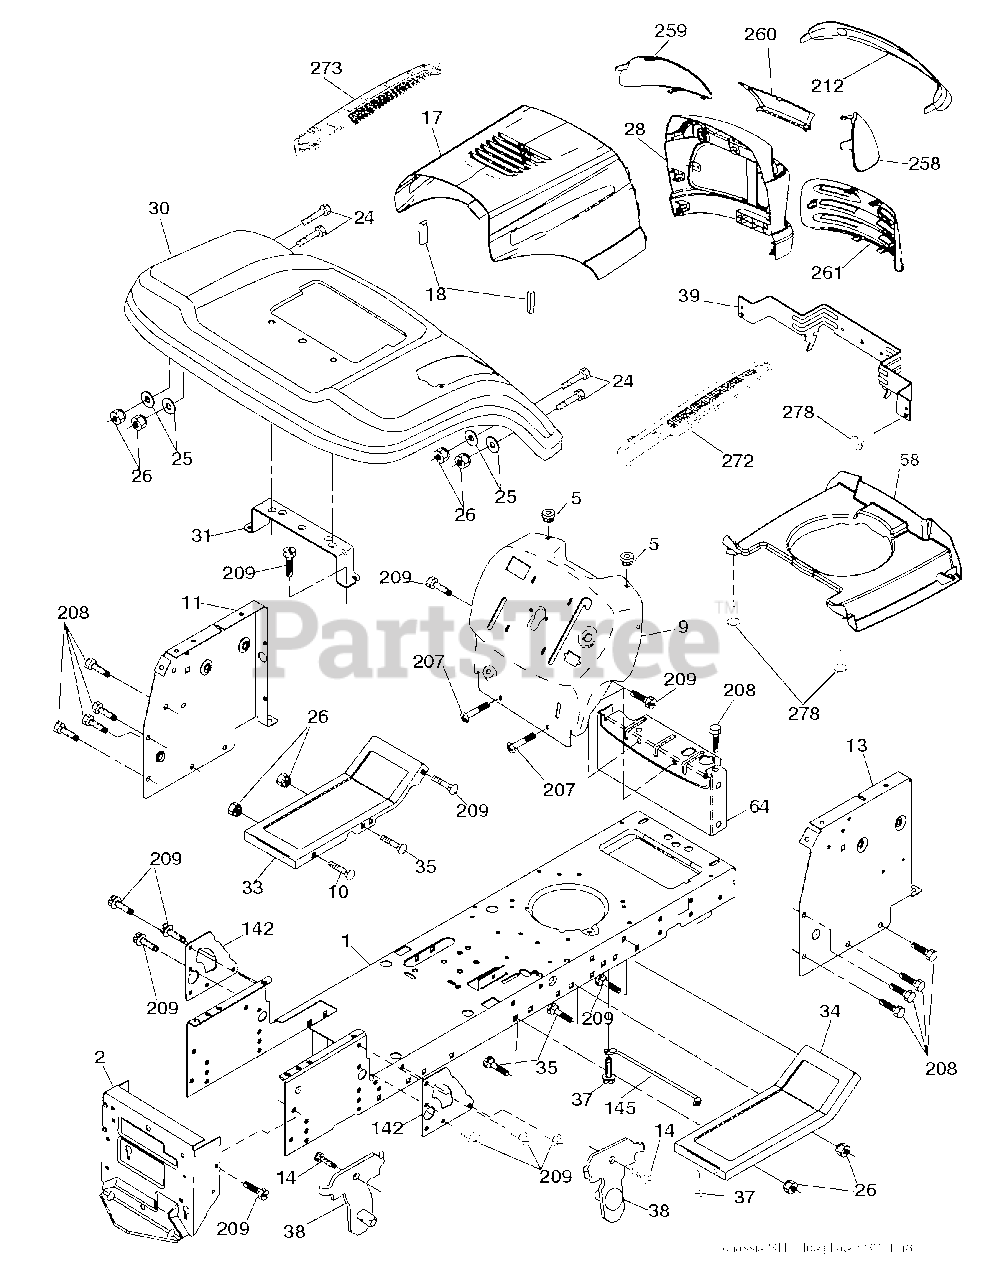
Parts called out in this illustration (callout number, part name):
1	CHASSIS STAMPING
2	DRAWBAR, 12GA
5	BUMPER.RUBBER.HOOD
9	DASH.STL.PLM.CAB.N/AMM.N/HM.05
10	BOLT D
11	PANEL.DASH.LH.LTX
17	HOOD.PNT.LASER.SV.LT.668
18	BUMPER.HOOD.LARGE.1.75"
25	WASHER
26	NUT
28	GRILLE.HUSQ.LASER.LT.668
30	FENDER.PNT.LTST.W/S.N/C.668ROS
31	BRACKET FENDER
33	FOOTREST.LH.BLACK
34	FOOTREST.RH.BLACK
37	SCREW LT
38	BRACKET.ASM.PIVOT.MOWER.REAR
39	BRACKET PIVOT
64	DASH LOWER
142	PLATE REINFORCEMENT
145	ROD.PIVOT.HOOD
207	SCREW, 5/16-18 X 1/2
208	SCREW 3/8-16X1/2
209	SCREW, 3/8-16X3/4
212	INSERT.LENS.REFLECTIVE
258	LENS LH
259	LENS LH
260	COVER.LENS.HUSQ.LASER.LT.498
261	INSERT.GRILLE.HUSQLASER.LT.498
272	VENT.HOOD.LASER.III.SD.RH
278	SCREW.#10 X 0.750.BOS
